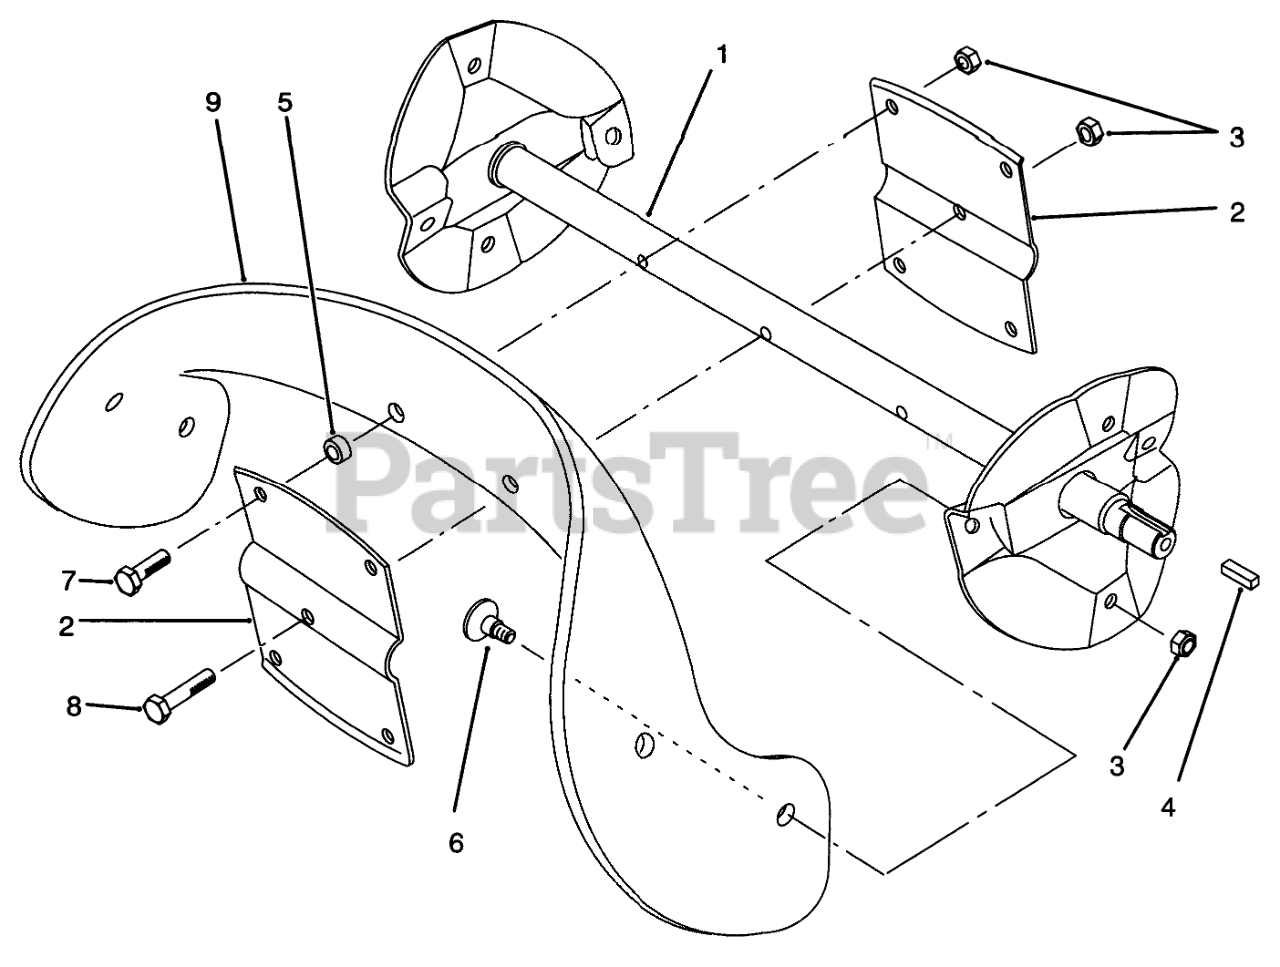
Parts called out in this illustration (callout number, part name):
1	Wa-Rotor
2	Rotor
3	NUT-LOCK, NI
4	KEY-SQUARE
5	SPACER-BLADE, ROTOR
6	SCREW
7	SCREW-HH
8	SCREW-HH
9	Blade-Rotor
